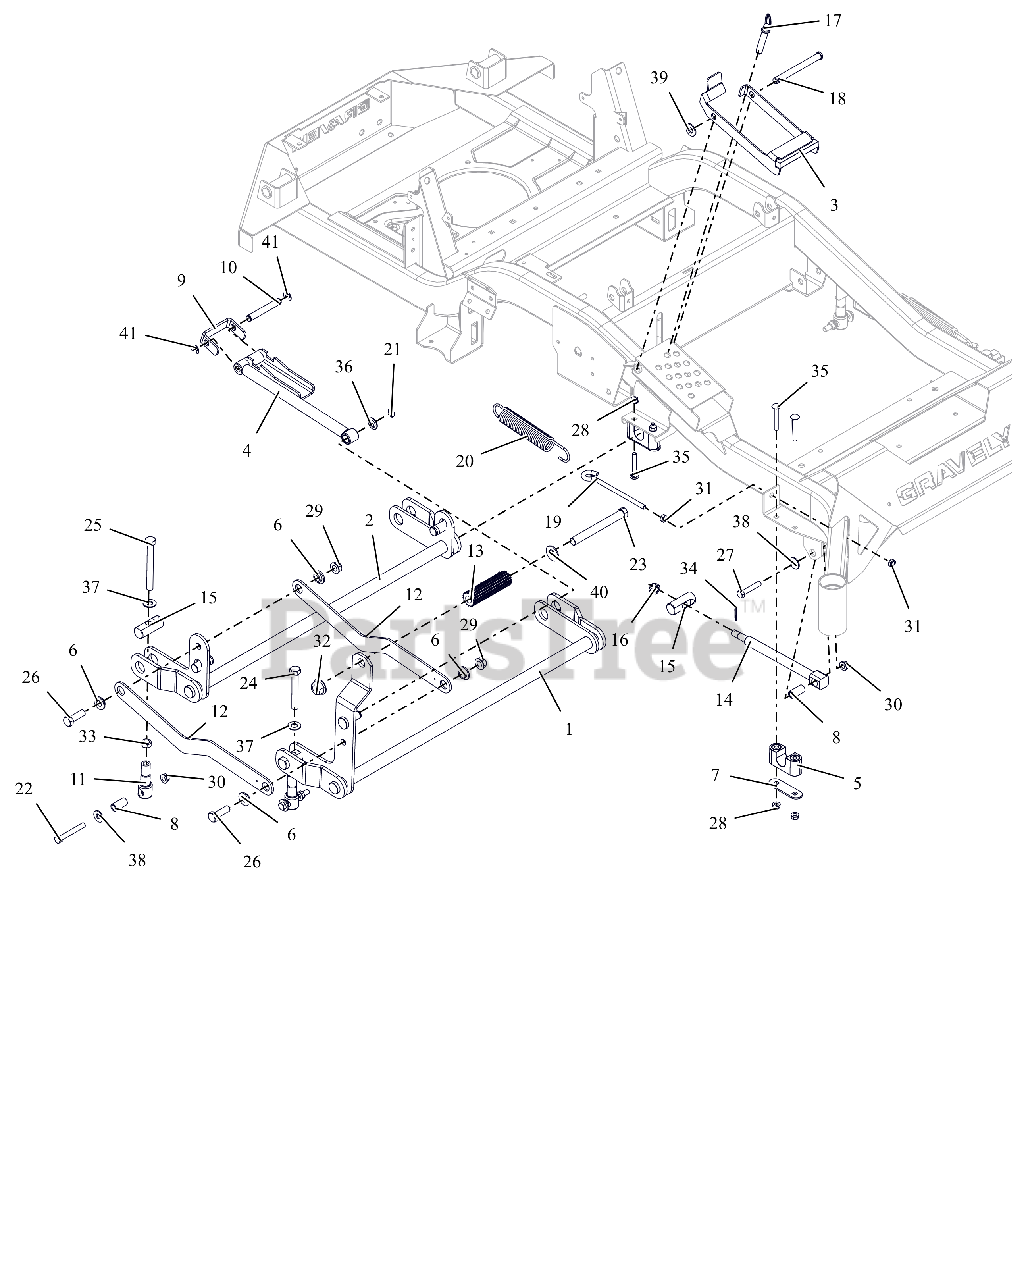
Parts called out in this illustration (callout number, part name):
1	WLDMT, FRONT DECK LIFT PIVOT
2	WLDMT, REAR DECK LIFT PIVOT
3	BRKT, HOC TRANSFER LOCK
4	WLDMT, HOC ARM
5	ASM-BUSHING, DECK LIFT
6	BSHG-FLG .515X.750X.310X1.120
7	PLATE, BEARING SUPPORT
8	SPACER, DECK LEVELING
9	BRKT, HOC LINE
10	ROD, HOC PIVOT
11	LINK, DECK LIFT FORMED
12	LINK, DECK LIFT
13	ROD, FOOT PEDAL (BLACK)
14	DRAG,LINK-HD
15	PIN, DECK LIFT
16	NUT-SL .50-13
17	PIN, .50 X 2.20 USABLE LG BALL
18	PIN, SLIC-.500X4.97X4.55 -ZC
19	BOLT,.38-16 X 5.25-.62 DIA EYE
20	SG-TENS .162X1.25X8.25 WLD 25
21	RG-RTNG-EXT .625X.050
22	BLT, HEX .38-16X2.75 G8 ZCC
23	BLT, HEX .62-11X5.50 G5 FBP
24	BLT, HEX 0.5-13X3.5F GR5 ZCC
25	BLT, HEX .50-13X4.50F G8 ZCC
26	BLT,HEX .50-13X1.50 G5 ZCC
27	BLT,HEX .38-16X2.00 G5 ZCC
28	NUT,LK-CTR-FLG .31-18 GF ZCC
29	NUT-LK-TOP-FLG .500-13 GF ZCC
30	NUT-LK-TOP-FLG .38-16 ZC120
31	NUT-JAM .375-16 G2 ZCC
32	NUT,FLG-TOP LK .625-11 FBP
33	NUT-JAM .500-13 G2 ZCC
34	PIN,CTR.12X1.25EXTPRSQCT ZC120
35	BLT, RHSSN.31-18X2.25 G5 ZCC
36	WSHR, FLT .630X1.005X.062 ZCC
37	WSHR, FLT .557X1.040X.102 ZCC
38	WSHR,FLT .438X1.00X.083 ZCC
39	WSHR,FLT .531X1.062X.095 ZCC
40	WSHRFLT 5/8SAE CARBHARD FBP
41	RG-RTNG-EXT .500X.042 (E)
